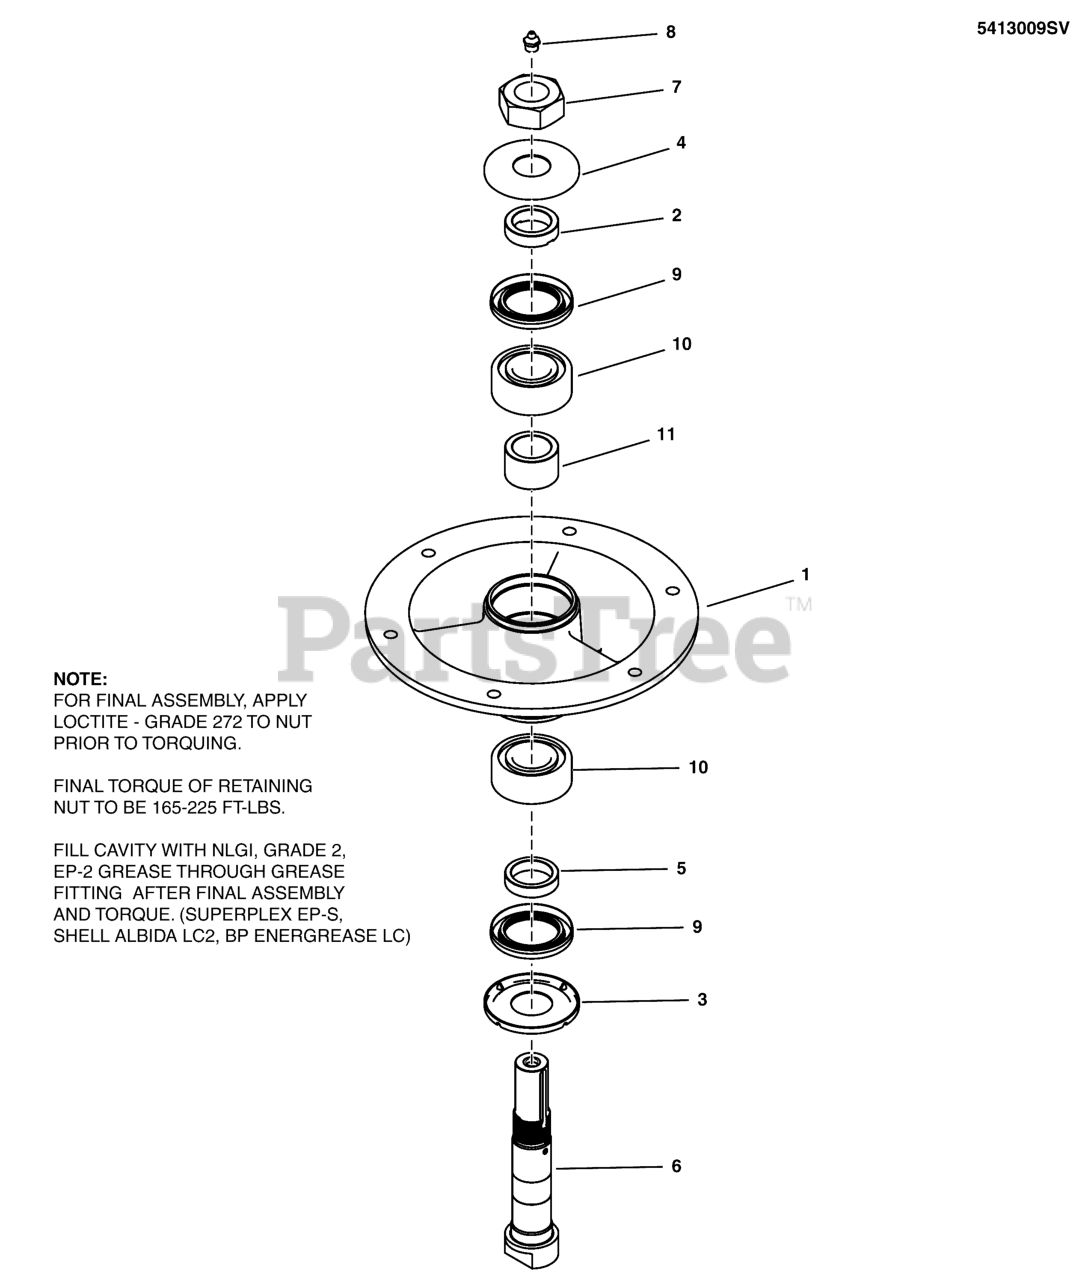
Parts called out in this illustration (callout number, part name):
1	HOUSING, SPINDLE, HD
2	SPACER (1.183 x 1.625 x 0.420)
3	SHIELD, TRASH, BOTTOM
4	SHIELD, TRASH, TOP
5	SPACER, 1.25 X 1.63 X .383
6	SHAFT, SPINDLE, HD
7	NUT, 1-1/ 8- 12 UNF, CZ
8	FITTING, 1/8 NPT STR, SHORT
9	SEAL, GREASE DOUBLE LIP
10	BEARING, #3206, DOUBLE ROW RADIAL BALL
11	SPACER, 1.183 x 1.625 x 1.030
